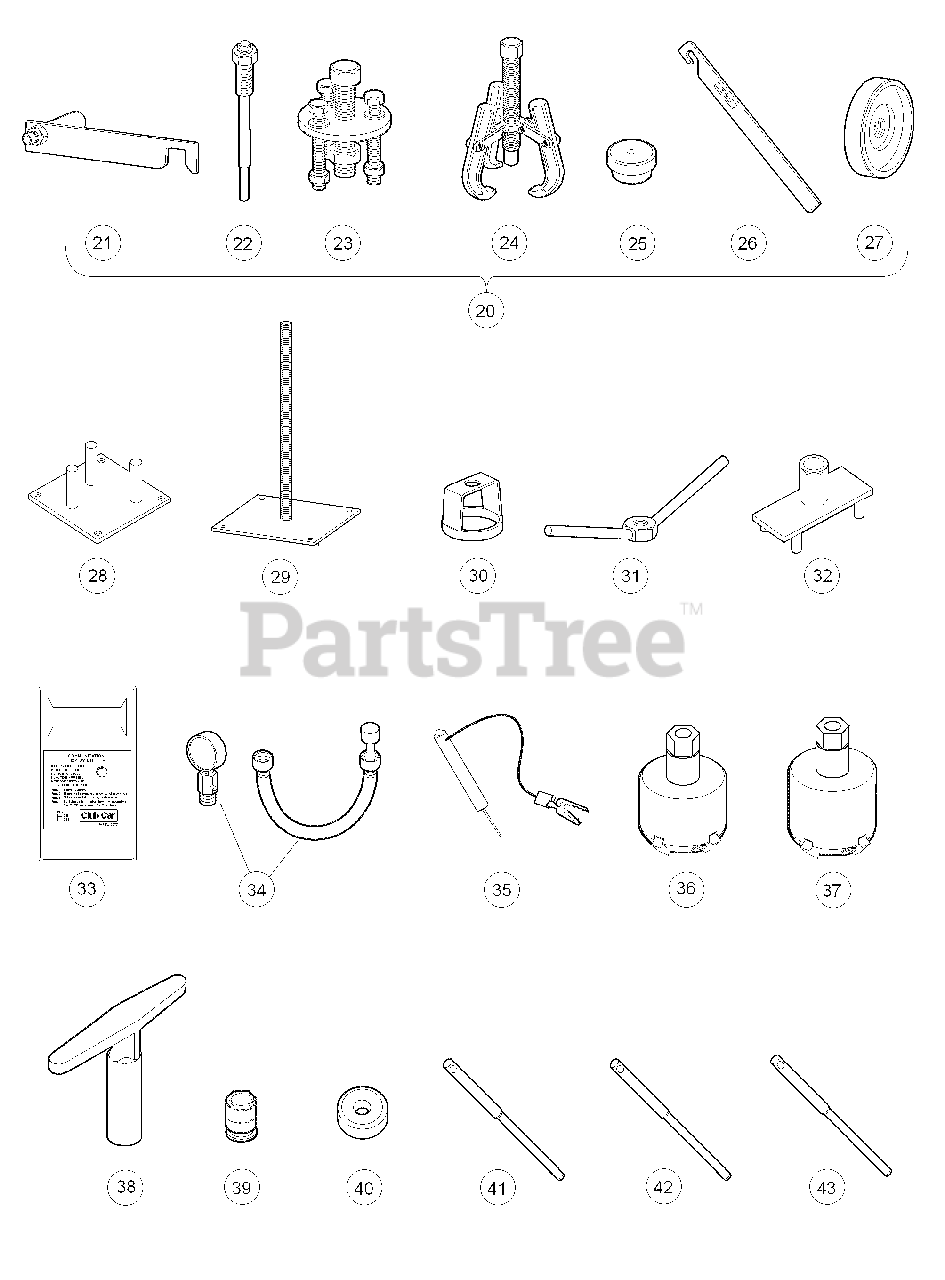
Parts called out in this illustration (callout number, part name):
20	Clutch Tool Kit
21	Clutch Alignment Tool
22	Drive Clutch Puller
23	Drive Clutch Hub Puller
24	Driven Clutch Cam Puller
25	Driven Clutch Puller Plug
26	Drive Clutch Holder Tool Assembly
27	Press Weldment
28	Drive ClutchFixed Sheave Tool
29	Driven Clutch Spring Compression Base
30	Driven Clutch Spring Compression Collar
31	Driven Clutch Spring Compression Nut
32	Drive Clutch Spider Removal Tool
33	Communication Display Module
34	Compression Gauge and Adapter
35	Continuity Tester
36	Cutter, Valve Seat, #122
37	Cutter, Valve Seat #115
38	Wrench, T, #505
39	Adapter, T-Wrench
40	Cutter, Valve Seat, 60 Degree
41	Pilot, 6.6 MM
42	Pilot, 6.62 MM
43	Pilot, 6.65 MM
